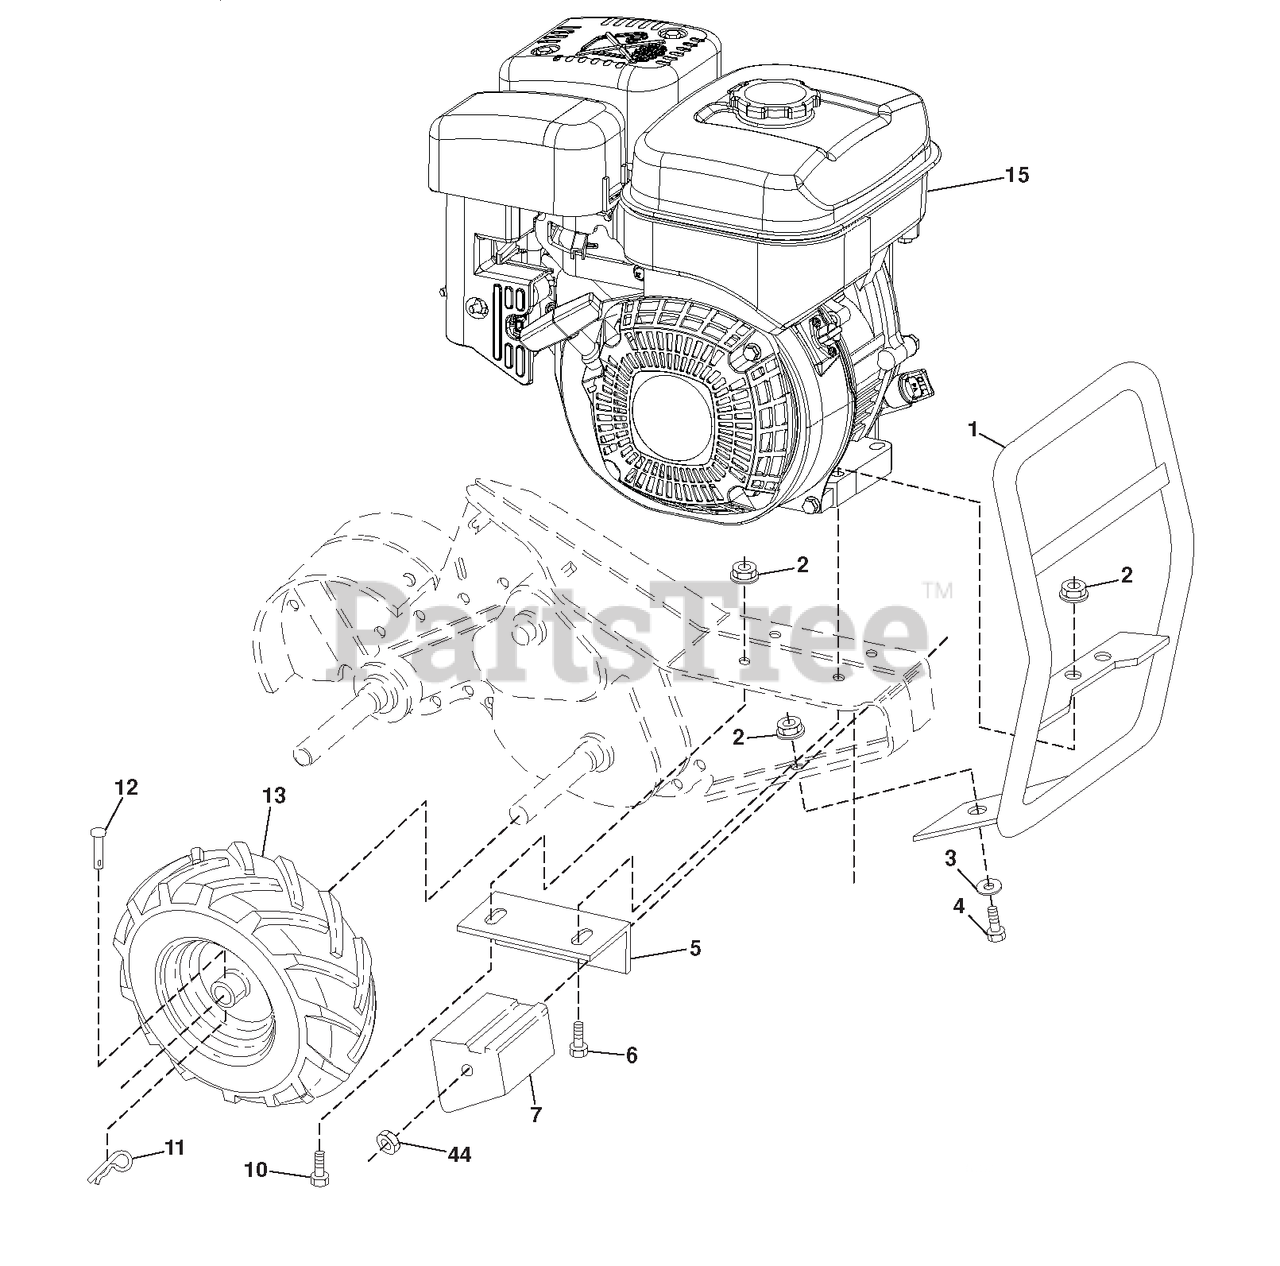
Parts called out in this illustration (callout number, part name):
2	Nut, Hex, Flangelock
3	Washer 11/32 x 11/16 x 16 Ga.
4	Bolt, Hex Head 5/16-18 x 3/4
5	Bracket, Reinforcement
6	Bolt, Fin Hex 5/16-18 unc x 1-
7	Counter Weight, RH
10	Bolt, Hex Head, Gr. 25/16-18 x
11	Retainer Spring
12	Rivet, Drilled
44	Nut Keps Hex 3/8-16 unc
